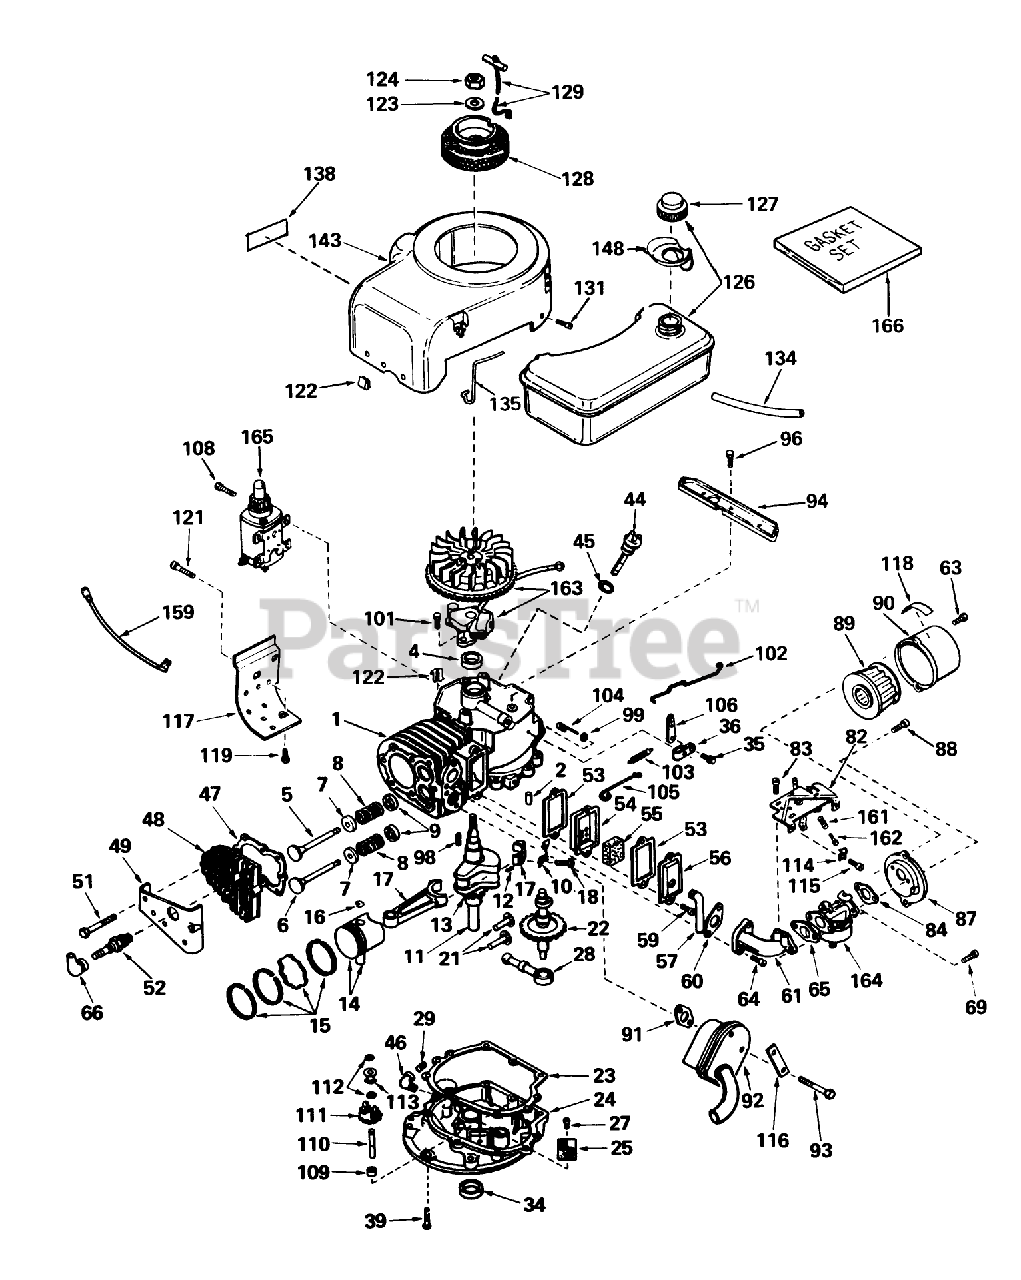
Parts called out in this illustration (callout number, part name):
1	Cylinder Assy. (Incl. Nos. 2, 4 44)
2	Pin-Dowel
4	Oil Seal
5	Valve, Intake (Standard)(Incl. No. 9)
5	Valve, Intake (1/32" oversize)(Incl. No. 9)
6	Valve, Exhaust (Standard)(Incl. No. 9)
6	Valve, Exhaust (1/32" oversize)(Incl. No. 9)
7	Cap-Spring, Valve
8	Spring-Valve
9	Keeper-Spring, Valve
10	Plate, Lock
11	Crankshaft Assy. (Incl. Nos. 12 13)(Model 935 only)
12	Pin, Groove
13	Gear-Crankshaft
14	Piston Pin Assy. (Incl. 2 of No. 16)(Standard)
14	Piston Pin Assy. (Incl. 2 of No. 16)(.010 oversize)
14	Piston Pin Assy. (Incl. 2 of No. 16)(.020 oversize)
15	ORing
15	Ring Set (.010" OS)
15	Ring Set (.020" OS)
17	Rod Assy., Connecting (Incl. Nos. 10 18)
18	Screw, Hex Hd.
21	Lifter-Valve
22	Screw
23	Gasket-Cover, Cylinder
24	Flange Assy., Mounting (Incl. Nos. 25, 27, 29, 34, 45 110)
25	Screen-Oil Filter
27	Screw
28	Pump, Oil
29	Plug-Drain, Oil (SQH 1/4-18)
34	Seal-Oil
35	Screw
36	Clamp-Lever, Governor
39	Screw (1/4-20 x 1-1/4)
44	Dipstick, Oil (Incl. No. 45)
45	Gasket
46	Elbow, 90
47	Gasket-Cylinder Head
48	CYLINDER HEAD
49	Cover-Head, Cylinder
51	Screw Hex Hd. Cap
52	Plug, Spark (Champion RCJ-8)
53	Gasket-Breather
54	Body-Breather
55	Element-Breather
56	Cover-Valve
57	Tube-Breather
59	Screw
60	Gasket-Intake
61	Pipe-Intake
63	Screw
64	Screw (T-30, 5/16-18x1-3/32)
65	Gasket
66	Cover-Spark Plug
69	Screw-Hex Hd.
82	Control Assy., Speed (Incl. Nos. 161 162)
83	Screw (10-24 x 9/16)
84	Gasket
87	Bracket
88	Screw (10-32 x 1/2)
89	Element
90	Body
91	Gasket Exhaust
92	Muffler
93	Screw Hex Hd.
94	Bracket-Blower Housing
96	Screw (1/4-20x19/32)
98	Key-Flywheel
99	Washer-Flat
101	Screw
102	Link Governor
103	Spring Governor
104	Rod, Governor (Incl. Nos. 146)
105	Link Governor Spring
106	Lever-Governor
108	Screw
109	Spacer
110	Shaft, Governor
111	Governor Gear ASM
112	Ring-Retaining
113	Spool-Governor
114	Conduit
115	Screw (10-32 x 3/8)
116	62513 SNWTHWR W/284
117	Emnsion, Blower Housing
118	Decal
119	Screw
121	Screw
122	51004 GIL ROTARY TI
123	Washer
126	Tank Assy., Fuel (Incl. No. 127)
127	Cap, Fuel
128	Hub Screen, Rope Starter
129	Rope Assy., Starter
131	Screw, Hex Hd.
134	Line-Fuel (8.62)
135	Clamp, Tank Holdown
138	480B GIL SNWTHWR O/
143	Housing Blower
148	Deflector-Fuel
159	SPOOL RETAINER (10-PK)
161	Spring-Compression
162	Screw
163	Magneto
164	Carburetor
165	Tine Shaft
166	Gasket Set
